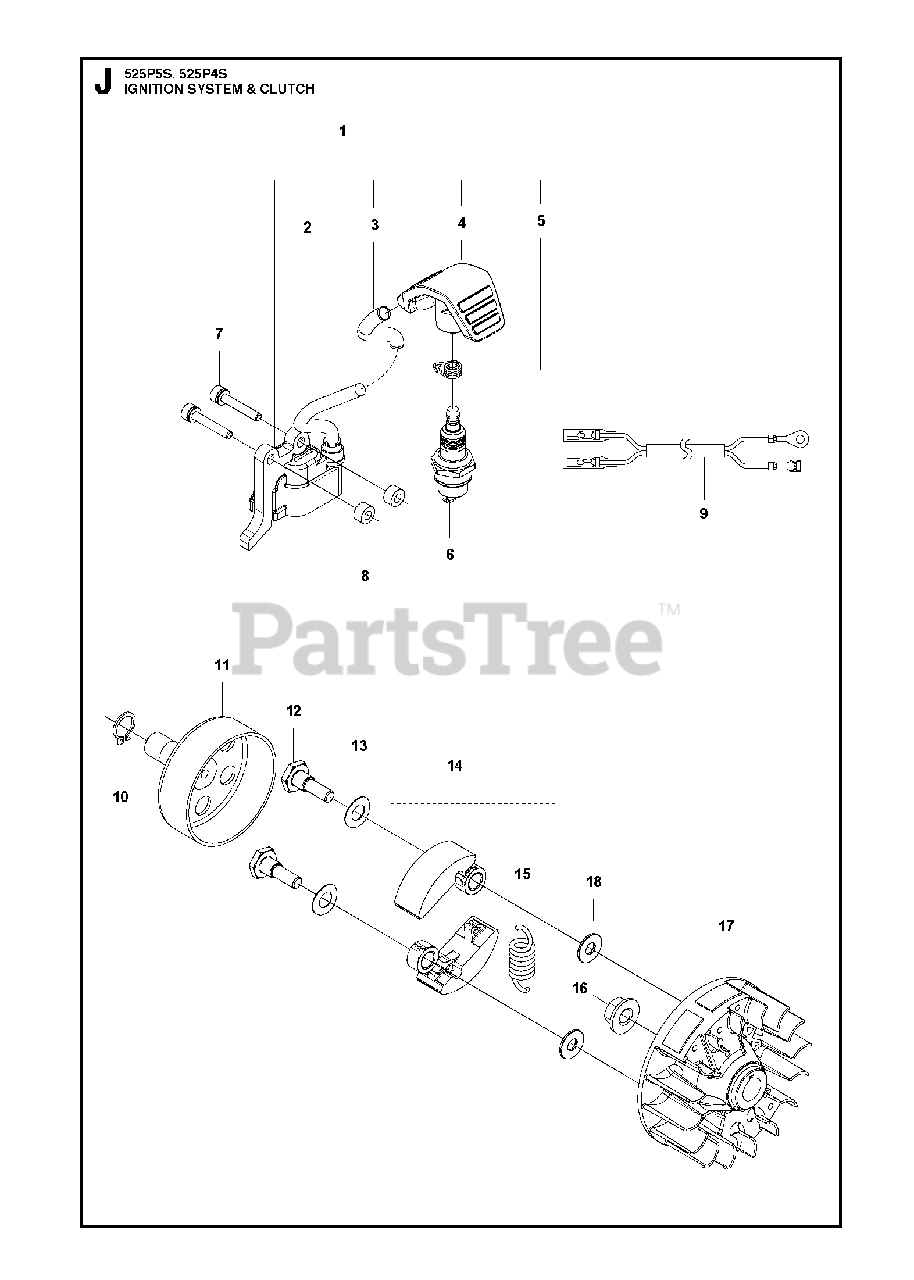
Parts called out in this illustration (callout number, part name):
1	IGNITION COIL ASSY
2	IGNITION CABLE
3	TUBE
4	SPARK PLUG CAP
5	SPRING
6	SPARK PLUG NGK BPMR-8Y
7	BOLT M4 X 25
8	SPACER
9	SHORT CIRCUIT CABLE
11	CLUTCH DRUM
14	CLUTCH ASSY Φ56
15	CLUTCH SPRING
16	NUT
